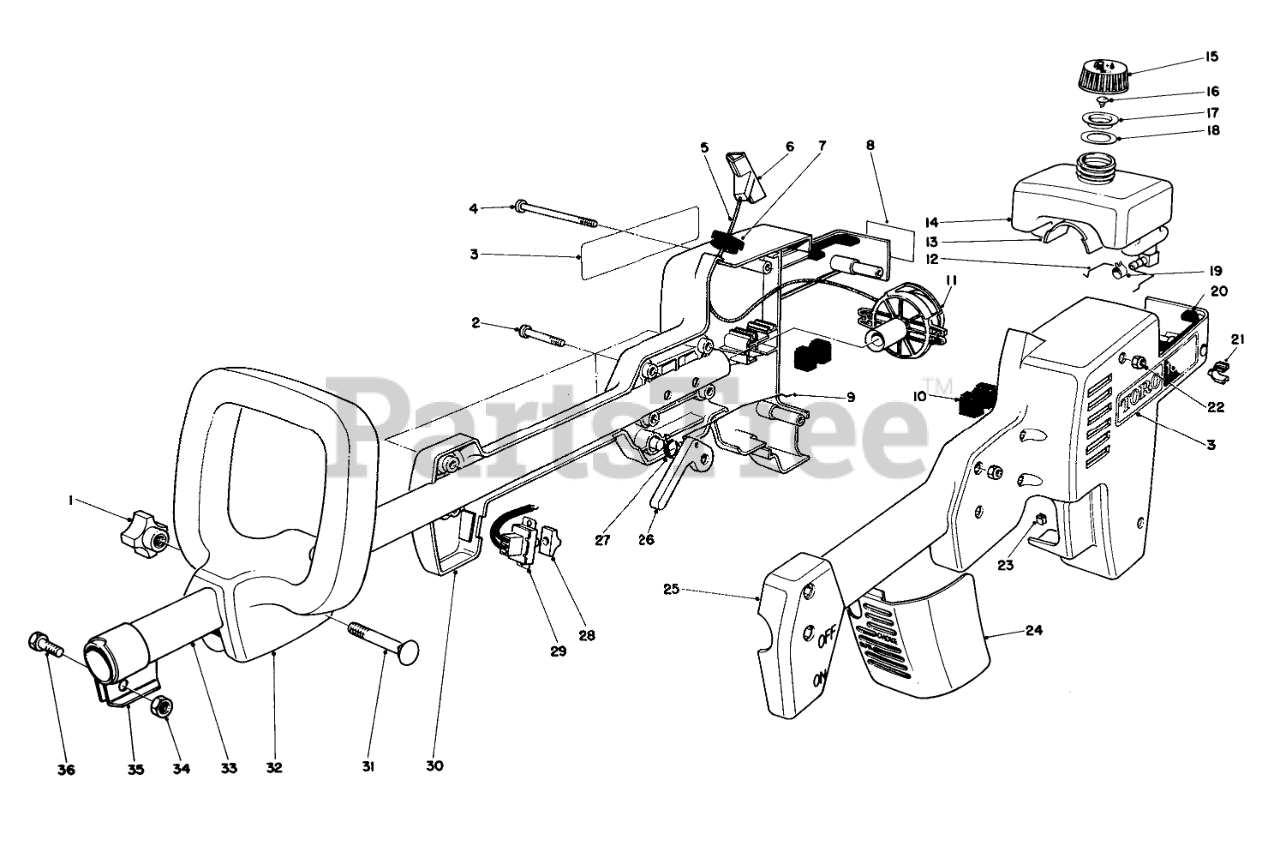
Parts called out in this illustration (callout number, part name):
1	Knob
2	SCREW-PPH
3	Decal
4	SCREW-PPH
5	Rope-Starter
6	Handle
7	Bushing Rope
8	Decal-Hot
9	Link-Throttle
10	Isolation Mount
11	Recoil Assembly(Incl. Ref. #5-7)
12	Clip-Crankcase Pad
13	Crankcase Pad
14	GAS TANK
15	Gas Cap Assy. (Incl. Ref. #17-19)
16	Valve
17	Insert
18	Gasket
19	CLAMP-HOSE
20	Bumper-Gas Tank
21	Grommet
22	NUT-LOCK, NI
23	Clip-S
24	Cover-Air Cleaner
25	Housing Engine L.H.
26	Lever Throttle
27	TORSION SPRING
28	SWITCH COVER-BLACK
29	SWITCH
30	Housing-Engine R.H.(Incl. Ref. #8)
31	BOLT-CARRIAGE
32	HANDLE SECONDARY
33	Tube-Upper Shaft
34	NUT-LOCK, NI
35	Clamp-Pole
36	SCREW-HH
